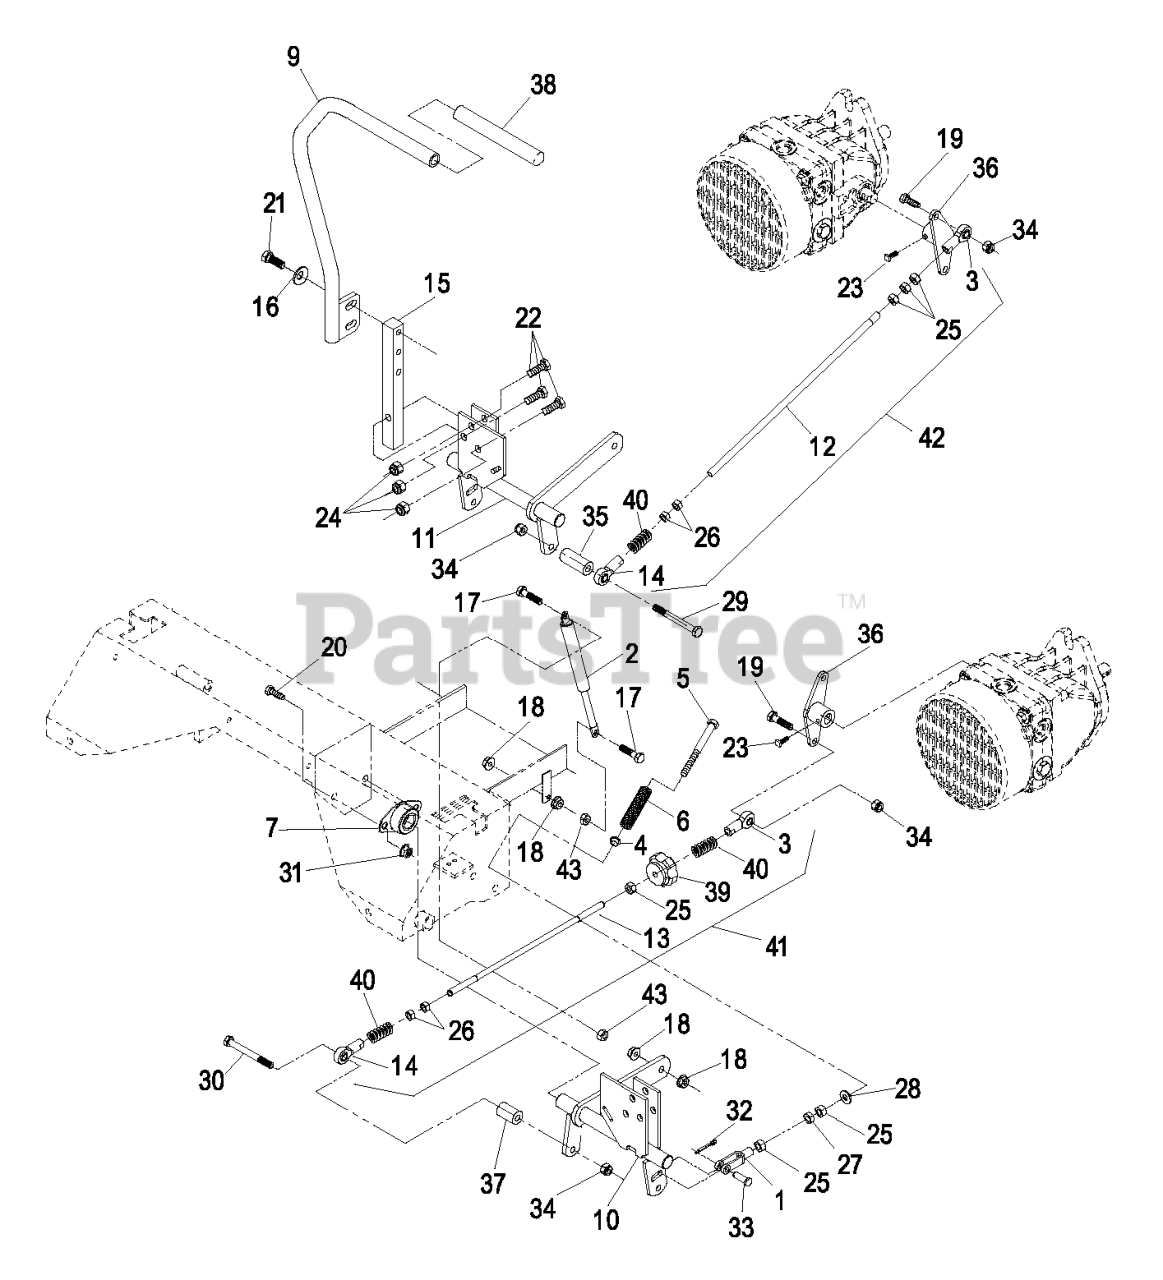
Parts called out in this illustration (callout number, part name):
1	YOKE-ADJUSTABLE
3	BALLJOINT-RH
4	BUSHING-FLANGED
5	BOLT-RETURN, NEUTRAL
6	SPRING-RETURN, NEUTRAL
7	BEARING-FLANGE, SIDE
9	ASM.RH LEVER/GRIP
12	LINK,XP HYDRO CONNECT RH
13	LINK,TRACKING ROD XP
14	BALLJOINT-LH
15	ARM-SHAFT, CONTROL
16	WASHER-BELLEVILLE
17	SCREW-HH
19	SCREW-HH
20	SCREW-HH
21	SCREW-HH
22	SCREW-HH
23	SCREW-SET
24	NUT-LOCK, NI
25	NUT-HEX
27	NUT-JAM
28	WASHER-FLAT
29	SCREW-HH
30	SCREW-HH
31	NUT-HHF, WHIZ
32	PIN-COTTER
33	PIN-CLEVIS
34	NUT-LOCK, NI
35	SPACER-CONTROL, HYD
36	ARM-CONTROL, HYDRO
37	SPACER-HYDRO CONTROL, LH
38	GRIP,CONTROL LEVER
39	KNOB-TRACKING
40	SPRING-COMPRESSION
41	TRACKING ROD ASM
42	RH HYD CONNECT LINK ASM
43	NUT-HEX
